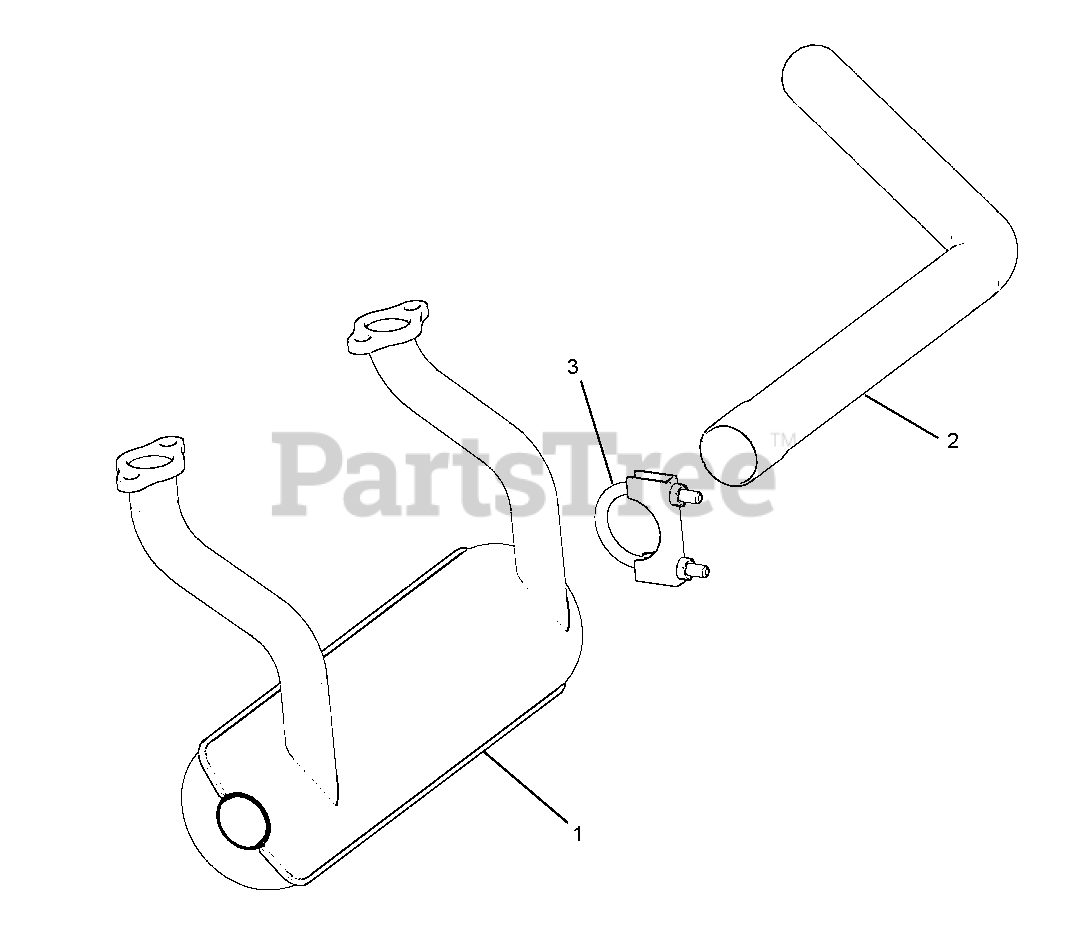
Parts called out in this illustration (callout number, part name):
1	MUFFLER, EH65
2	TAILPIPE, EH65
3	MUFFLER CLAMP
